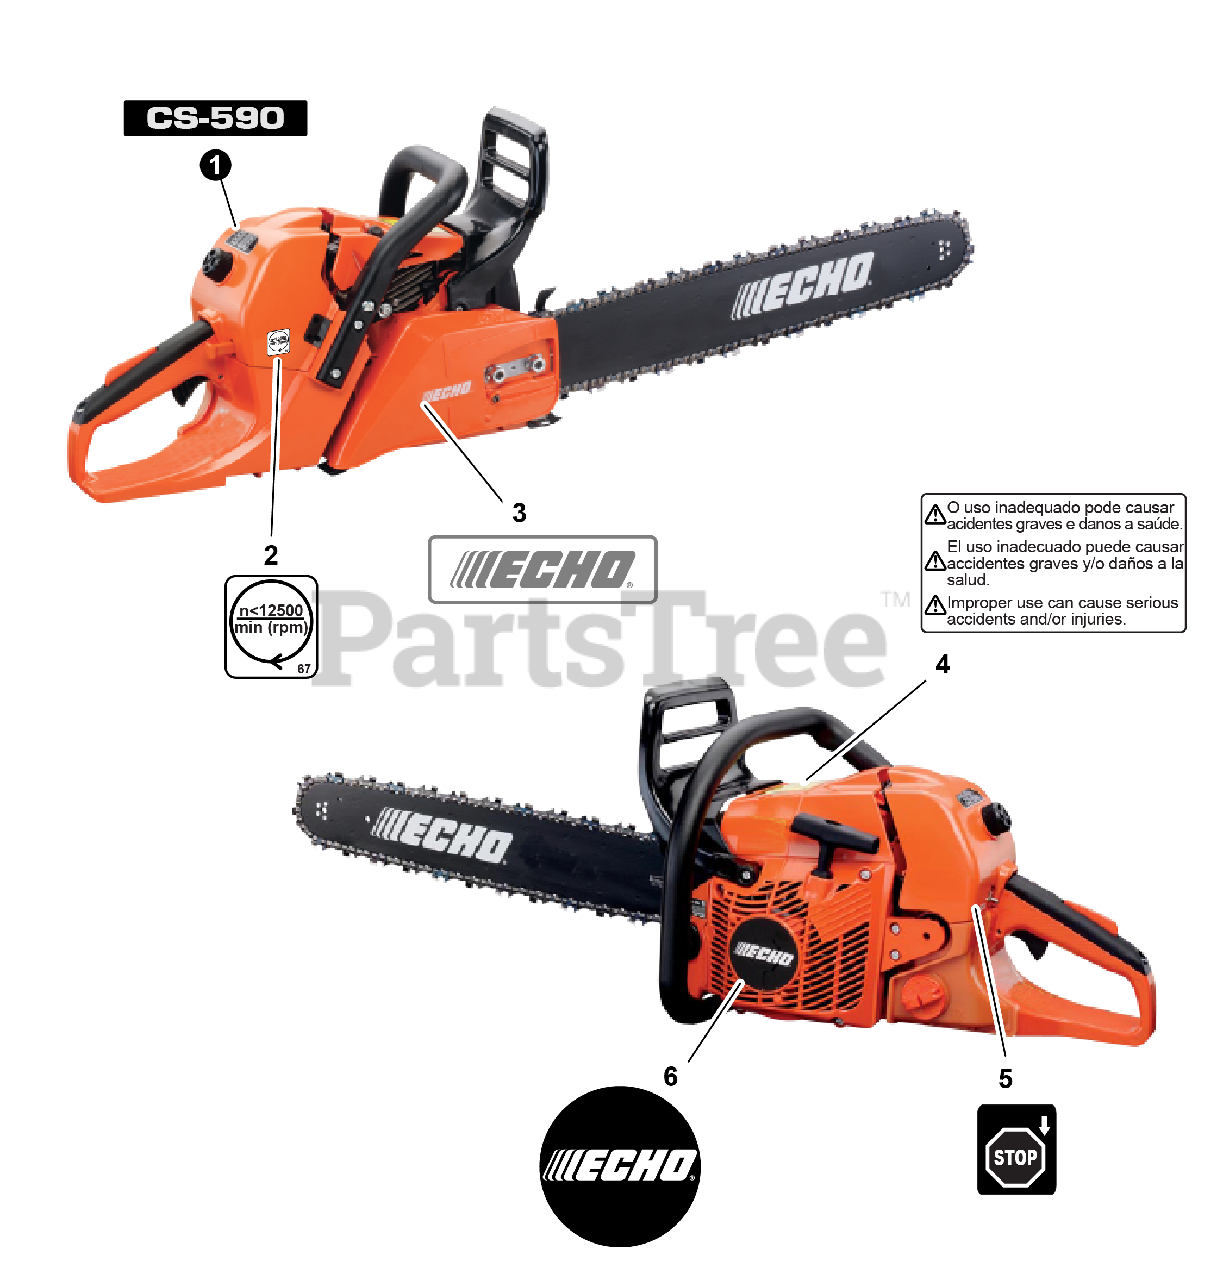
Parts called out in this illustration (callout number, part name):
1	LABEL CS-590
2	LABEL, CAUTION
3	LABEL, ECHO
4	LABEL, CAUTION
5	LABEL, ON-OFF
6	LABEL, RECOIL STARTER
